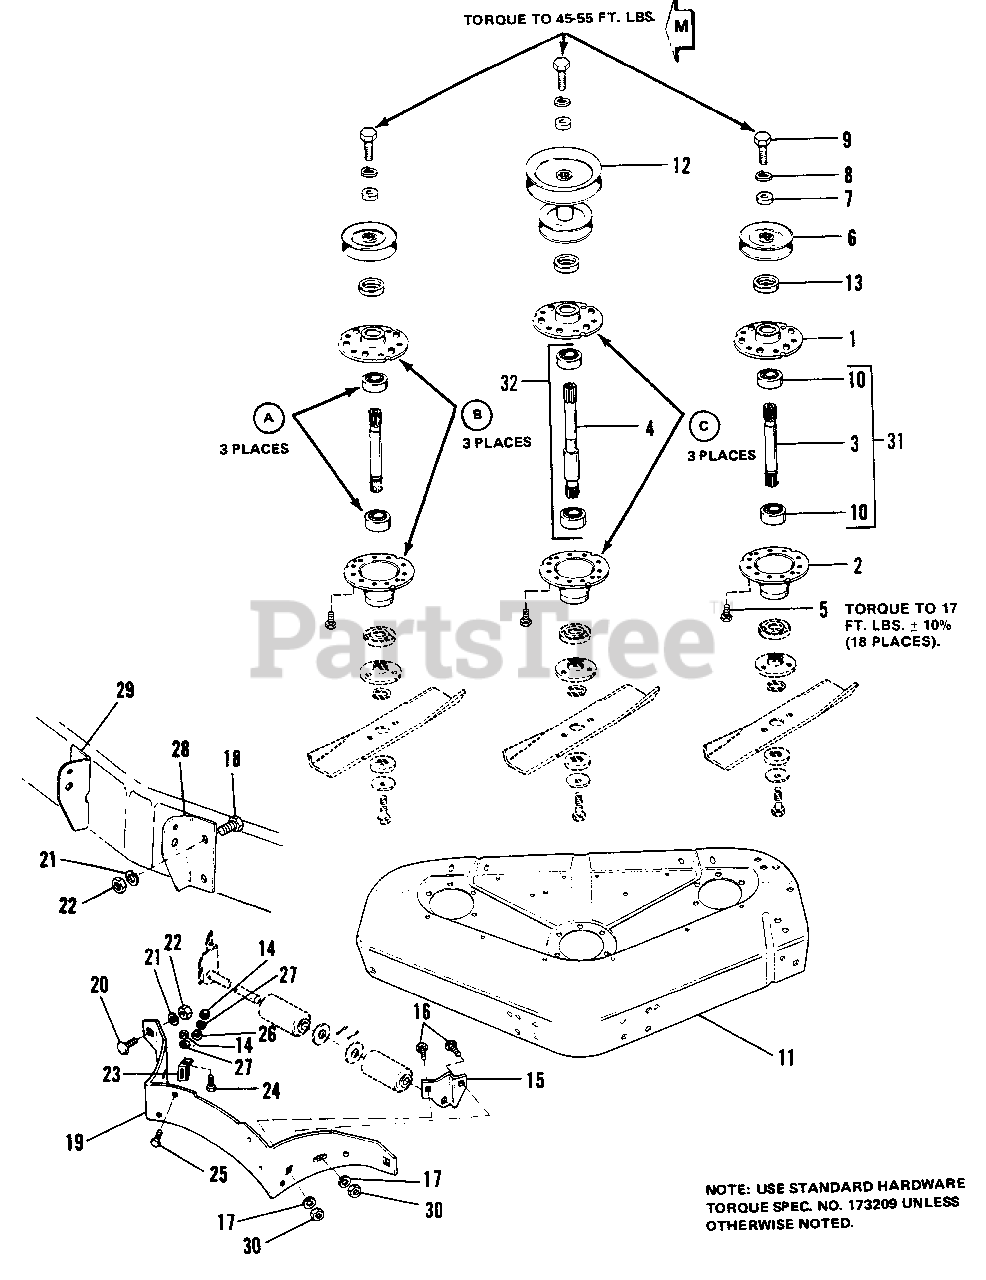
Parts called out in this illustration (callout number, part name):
1	HOUSING, Top
2	HOUSING, Bottom
3	SHAFT, Arbor
4	SHAFT, Arbor, Center
5	SCREW, Hex Whsr. Hd., 5/16 x 5/8
6	PULLEY ASSY, Deck Drive
7	WASHER
8	LOCKWASHER, 7/16
9	CAPSCREW, Hex Hd., 7/16-14 x 1-1/4
11	HOUSING, 42"
12	PULLEY ASSY
13	SHIELD, Bearing Upper, Arbor
14	NUT, Hex, Full, 1/4-20
15	BRACKET, Roller, L.H.
16	BOLT, Carriage, 5/16-18 x 3/4
17	LOCKWASHER, 5/16
18	CAPSCREW, Hex Hd., 3/8-16 x 3/4
20	BOLT, Carriage, 3/8-16 x 3/4
21	LOCKWASHER, 3/8
22	NUT, Hex, Full, 3/8-16
23	CLIP, Baffle
24	SCREW, Thd. Cutting, 1/4-20 x 7/8
25	CAPSCREW, Hex Hd., 1/4-20 x 5/8
26	WASHER, Plain, 1/4
27	LOCKWASHER, 1/4
28	BRACKET, L.H.
29	BRACKET, R.H.
30	NUT, Hex, Full, 5/16-18
31	SHAFT & BEARING ASSY
32	SHAFT & BEARING ASSY, Center
